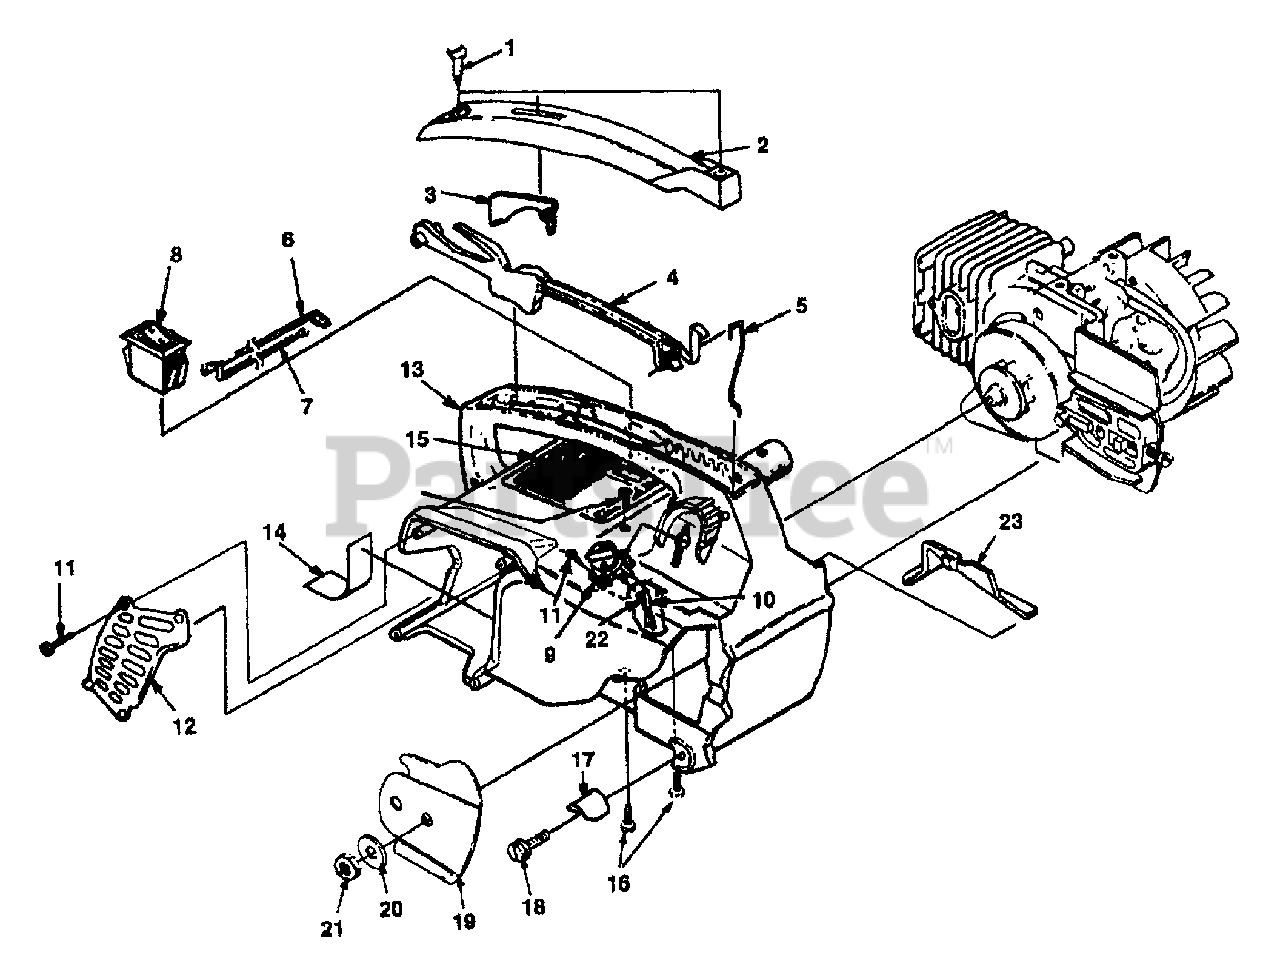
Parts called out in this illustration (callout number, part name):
1	SCREW-Pan, plastite (#10-16 X 3/4")
2	COVER-Handle
3	LOCK-Trigger
4	TRIGGER
5	ROD-Throttle
6	LEAD-w/Flag Term.
7	LEAD-w/Ring Term.
9	OIL VALVE
10	TUBING-Rubber (4 1/4")
11	SCREW-Pan plastite (#6 X 3/8")
12	SHIELD-Muffler
13	HOUSING-Engine
14	TAPE
15	DECAL-Warning
16	SCREW-Torx, taptite (10-24 X 3/4")
17	STOP-Chain
18	SCREW-Torx, plastite (#10 X 3/4")
19	PLATE-Guide Bar
20	WASHER-Flat
21	NUT-Hex
22	TUBING Rubber (8")
23	COVER- Air Filter
